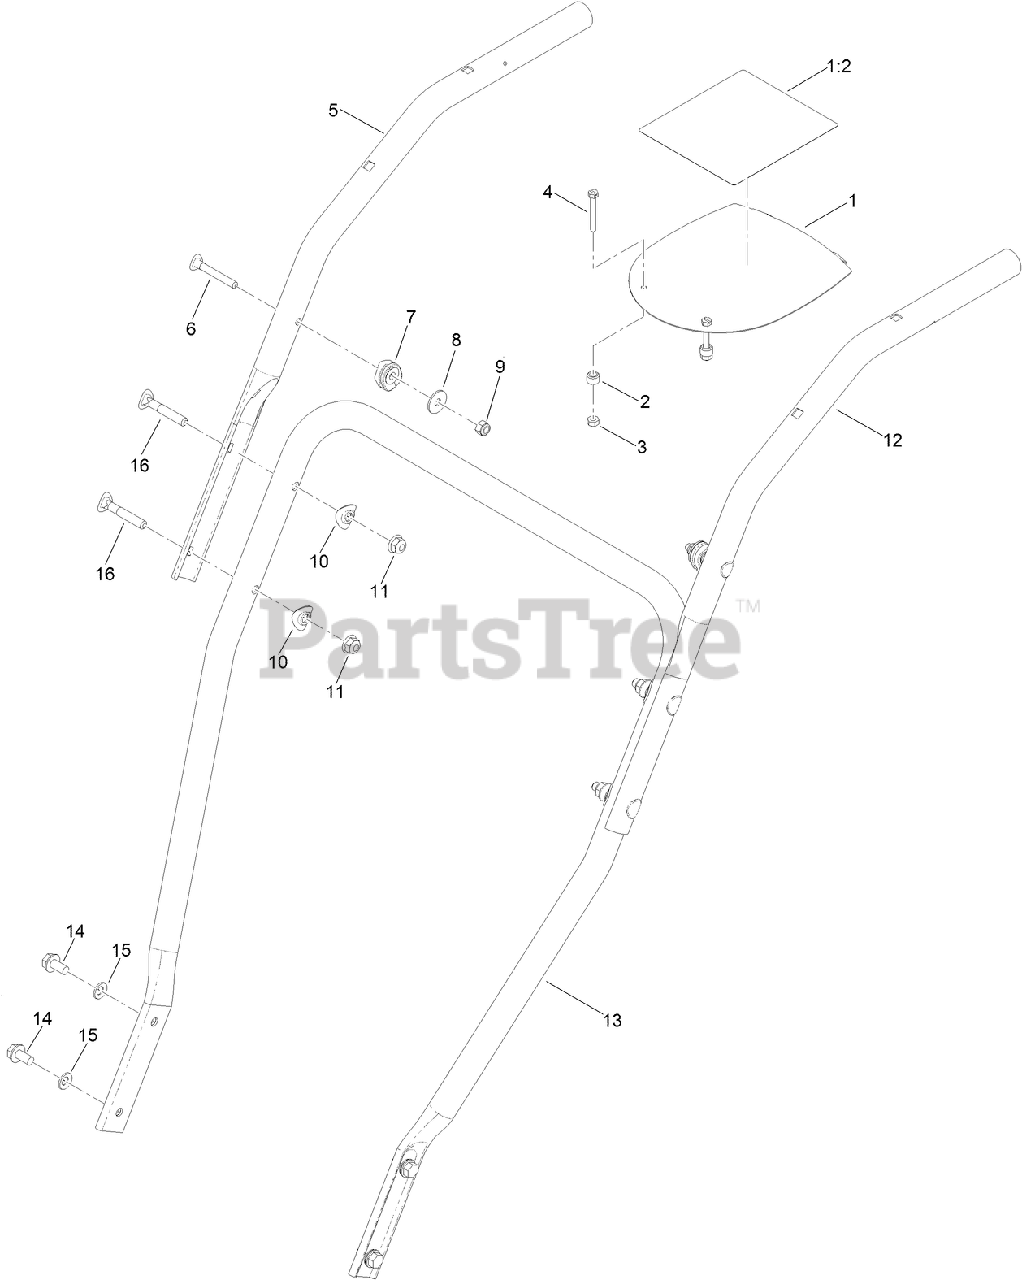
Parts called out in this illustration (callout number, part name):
1	PANEL-CONTROL
1:2	DECAL-WARNING
2	SPACER-BLADE, ROTOR
3	NUT-LOCK, NI
4	SCREW
5	HANDLE-UPPER, RH
6	SCREW
7	CLAMP-CABLE
8	WASHER-PLAIN
9	NUT-LOCK, NI
10	WASHER
11	NUT-HF, NI
12	HANDLE-UPPER, LH
13	HANDLE-LOWER
14	SCREW-HWHTF
15	WASHER-BELLEVILLE
16	SCREW-HANDLE
